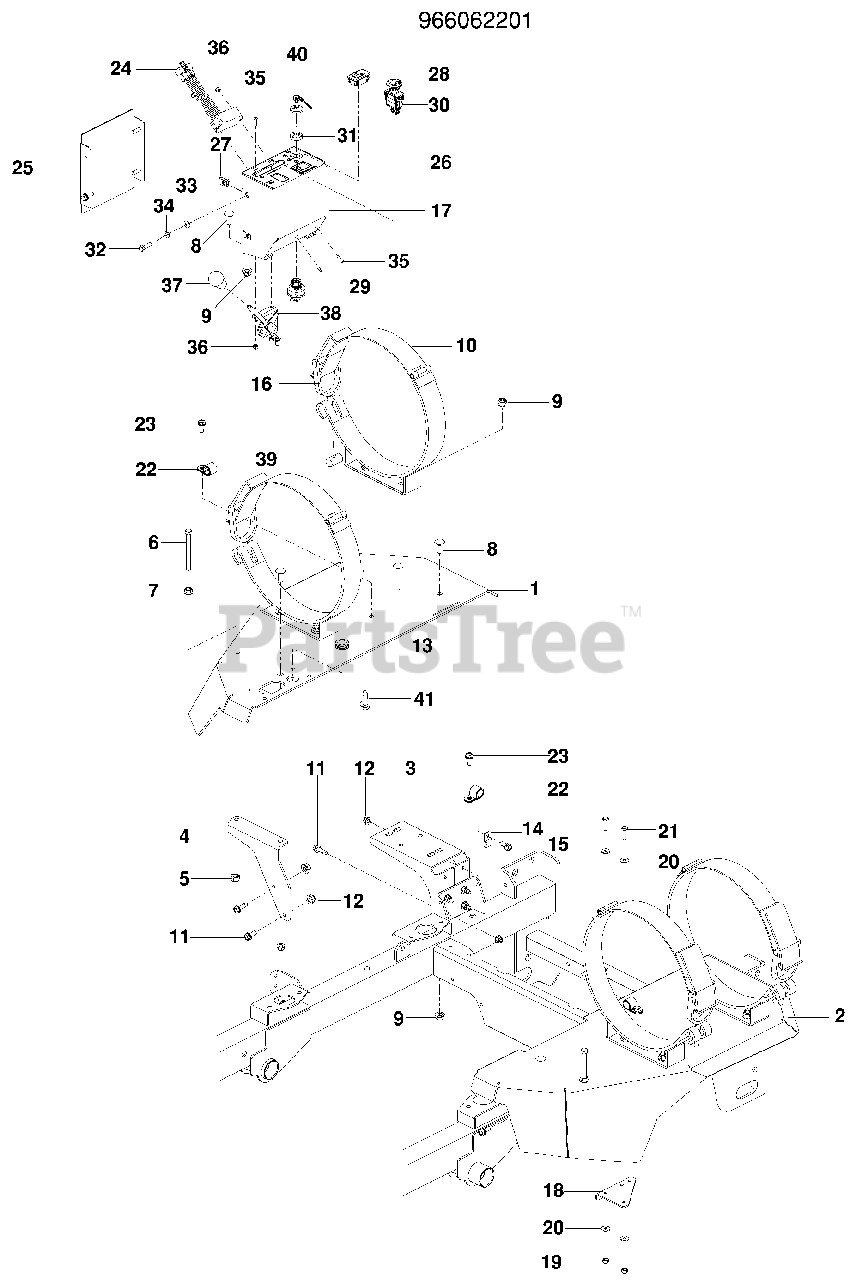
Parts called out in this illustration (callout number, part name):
1	FENDER, LP RT
2	FENDER, LP LT
3	MOUNT, TANK RR
4	SUPPORT, LP FENDER RT
5	NUT 3/8-16 HEX CNTRLK
6	HCS 3/8-16 x 3½
7	NUT 3/8-16 HEX WHIZLK
8	BOLT 3/8-16 x 1 RD HD
9	NUT 3/8-16 HEX FLG NYLOC
10	BRACKET, LP TANK
11	BOLT 5/16-18 x 1 THD FRM
12	NUT 5/16-18 HEX FLG NYLOC
13	GROMMET, FUEL LINE
14	CLAMP, DOUBLE TUBE
15	SCREW 5/16-18 x ¾ HEX FLG
16	TOGGLE ASSY
18	BRACKET, REGULATOR
19	NUT ¼-20 HEX NYLOC
20	WASHER ¼ FLAT
21	BOLT ¼-20 x 1 HEX HD
23	BOLT 5/16-18 x ¾ THD FRM
24	TIMER, SEAT
25	COVER, LP DASH
26	DECAL, LP CONTROL
27	RETAINER, U TYPE
28	HOUR METER
29	SWITCH, IGNITION
30	SWITCH, PTO 10 AMP
31	CAP, IGNITION SWITCH NUT
32	BOLT 5/16-18 x 1 HEX HD
33	WASHER 5/16 SAE FLAT
34	WASHER 5/16 SLW
35	SCREW 10-24 x ¾ SKT HD
36	NUT 10-24 HEX NYLOC
38	CABLE, THROTTLE
39	NUT, TOGGLE
41	SCREW 3/8-16 x 1 HEX HD
